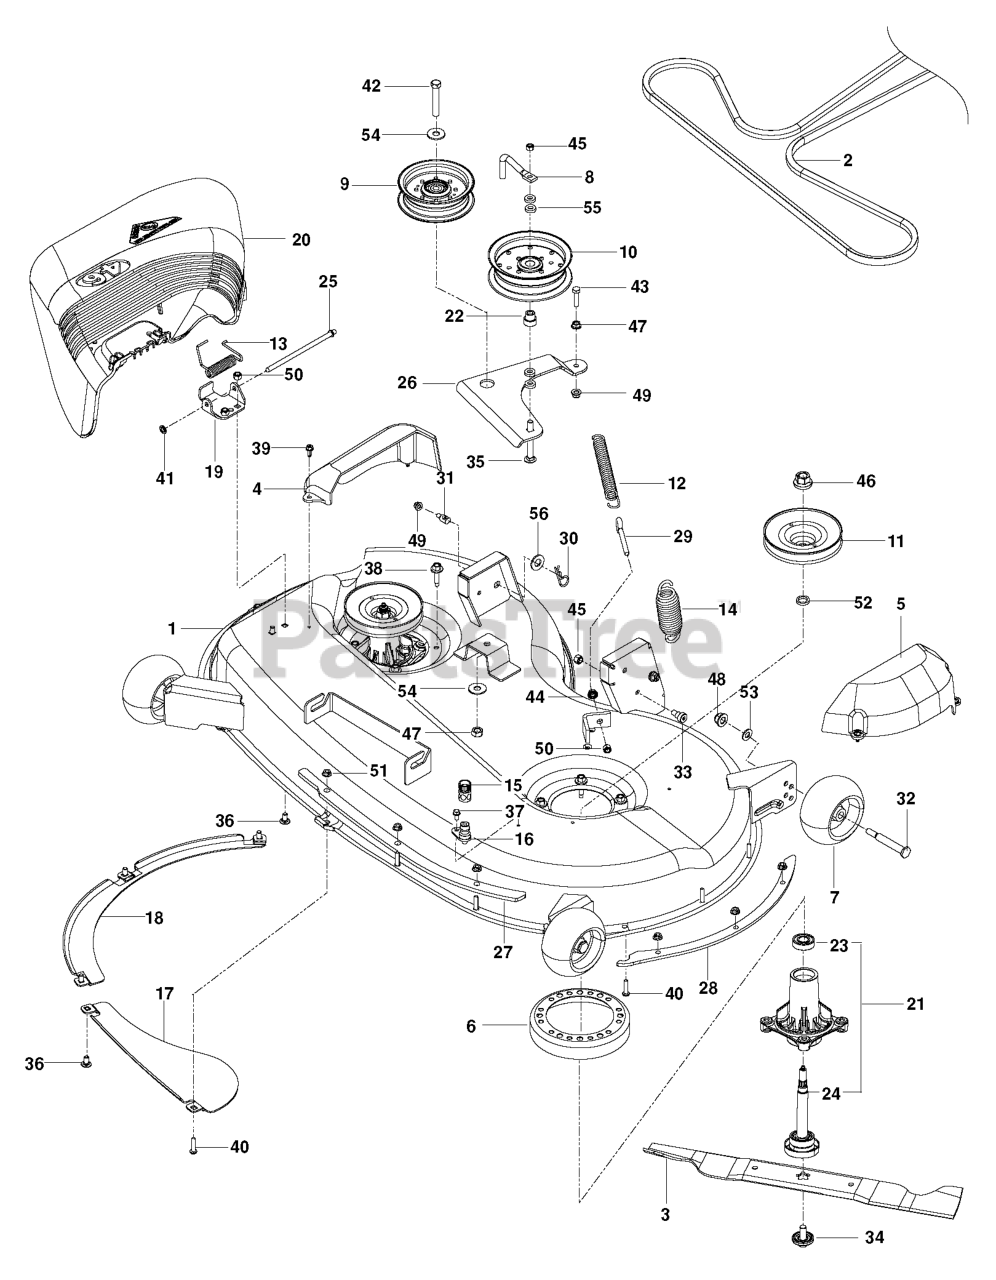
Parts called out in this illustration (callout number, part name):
1	DECK SVC 46"W/DECALS ORG
3	BLADE.MOWER.46".HI.LIFT
4	COVER.MANDREL.RH.46"
5	COVER.MANDREL.LH.46"
6	STRIPPER.MANDREL.ROUND.BLACK
7	RP WHEEL. GUAGE RALLY
8	BELT KEEPER 5"
9	PULLEY.IDLER.MWR.STATI.LH
10	PULLEY, IDLER
11	RP.PULLEY, DECK
12	SPRING, DECK BELT
13	SPRING, TORSION
14	SPRING
15	COUPLING.QUICK CONNECT
16	PORT.WASHOUT
17	BAFFLE CENTER FRONT
18	BAFFLE FRONT RH
19	BRKT.DEFLECTOR.38"2005+
20	SHIELD.DEFLECTOR.MOWER.46"BLAC
21	MANDREL ASM
22	IDLER BUSHING
24	SHAFT ASM W/LOWER BEARING
25	ROD, HINGE
26	ARM, IDLER BLK
27	PLATE.REINFORCE.46.BOLT.ONX431
28	PLATE.REINFOR.46.SIDEBOLT.X431
29	EYE BOLT 5/16 X 3.50
30	HAIRPIN #4
31	STUD.FASTNER.W/ANTI-ROTATE
32	BOLT.SHOULDER.3/8-16X3-5/8.
33	SB 3/8-16 X 3/8 SKT HD ZD
34	BOLT.WASHER.ASM.7/16-2
35	CARRIAGE BOLT 3/8-16 X
36	RP BOLT 5/16-18 X3/4 ZN/YEL GR
37	SCREW #10 X 1/2 SELF TAPPING
38	SCREW, WASHER HEAD
39	SCREW.1/4-20X5/8
40	SCREW.BUTTONHEAD.1/4-20X1
41	NUT PUSH M
42	BOLT.HEX.7/16-14
43	BOLT.5/16-18X1-1/4 FULL.THREAD
44	NUT 5/16C WHIZ
45	NUT HEX 3/8-16 NYLON, THIN
46	NUT.FLANGE.LOCK.TOP
47	7/16-14 HEX NUT W/NYL RING ZD
48	NUT LOCK FLG 3/8-16 UNC
49	5/16-18 NYLOC FLANGE NUT
50	NUT.71038.31-18.HEX.NYLOCK
51	NUT T
52	WASHER.SPACER.MANDREL
53	WASHER
54	WASHER 7/16 FLAT ZD
55	WASHER 3/8 X 3/4 X .187 TK
56	WASHER
